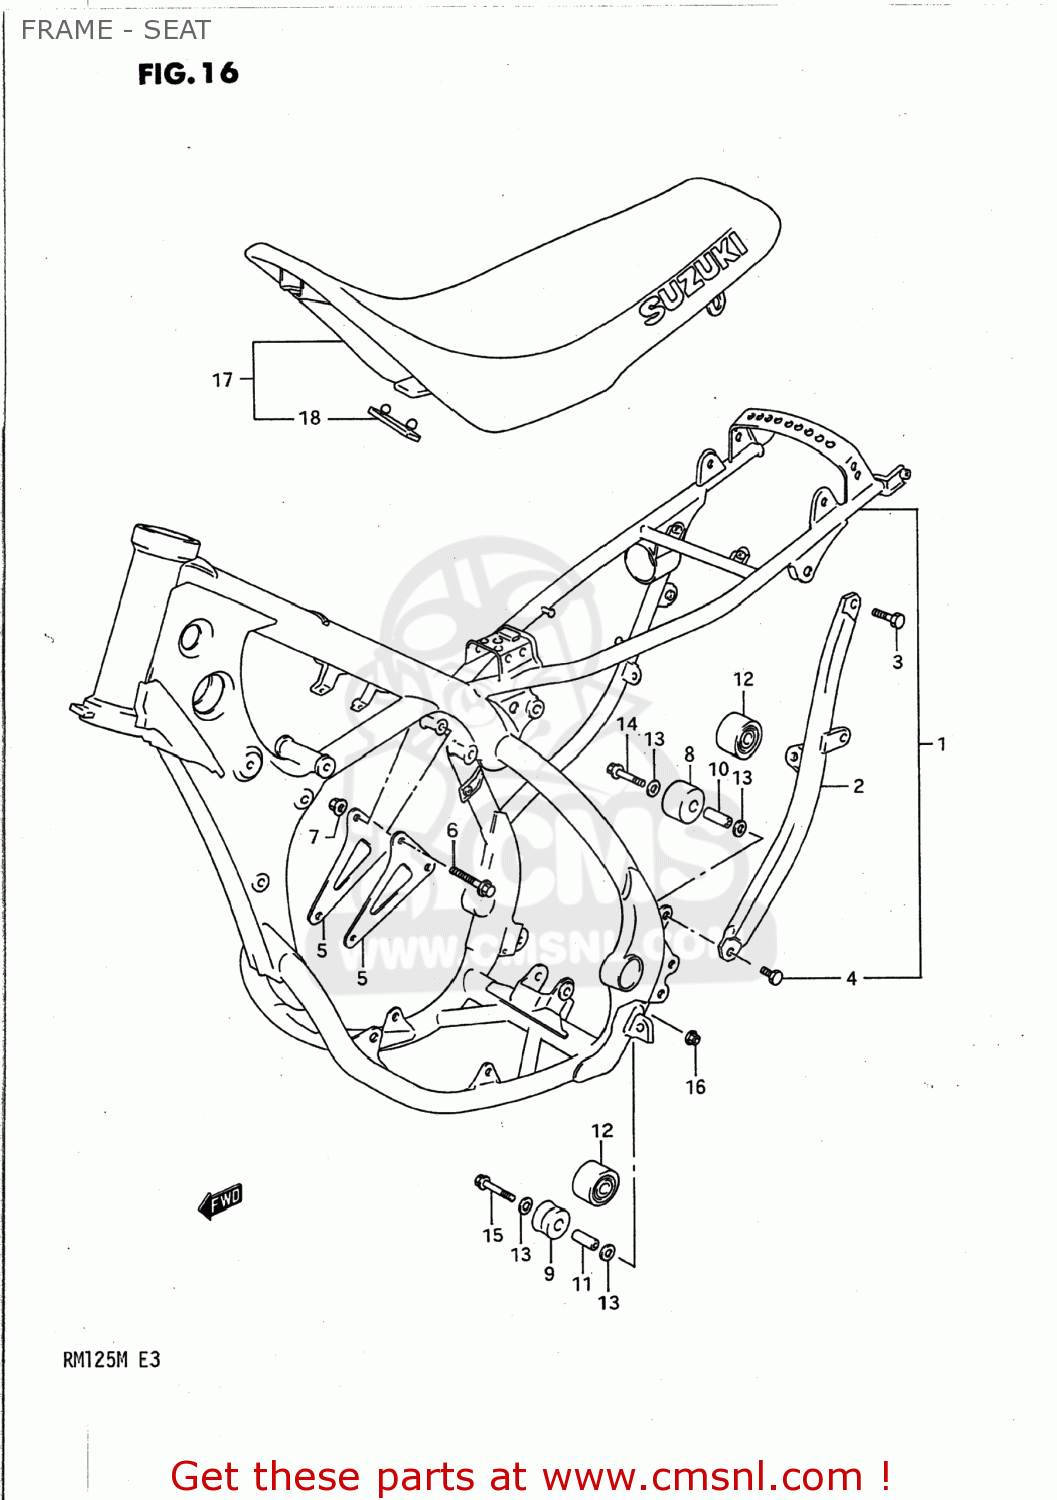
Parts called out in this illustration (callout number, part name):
1	FRAME
2	TUBE,FRAME SIDE,LEFT
3	BOLT(8X22)
4	BOLT
5	PLATE,ENG MTG UPR
6	BOLT 8X40
7	NUT
8	ROLLER,CHAIN CONTROL
9	ROLLER,CHAIN CONTROL
10	SPACER (8.6X13.8X28)
11	SPACER(8.6X12X25.5)
12	ROLLER,CHAIN
13	WASHER
14	BOLT(8X41)
15	BOLT(8X45)
16	NUT
17	SEAT SET
18	CUSHION
